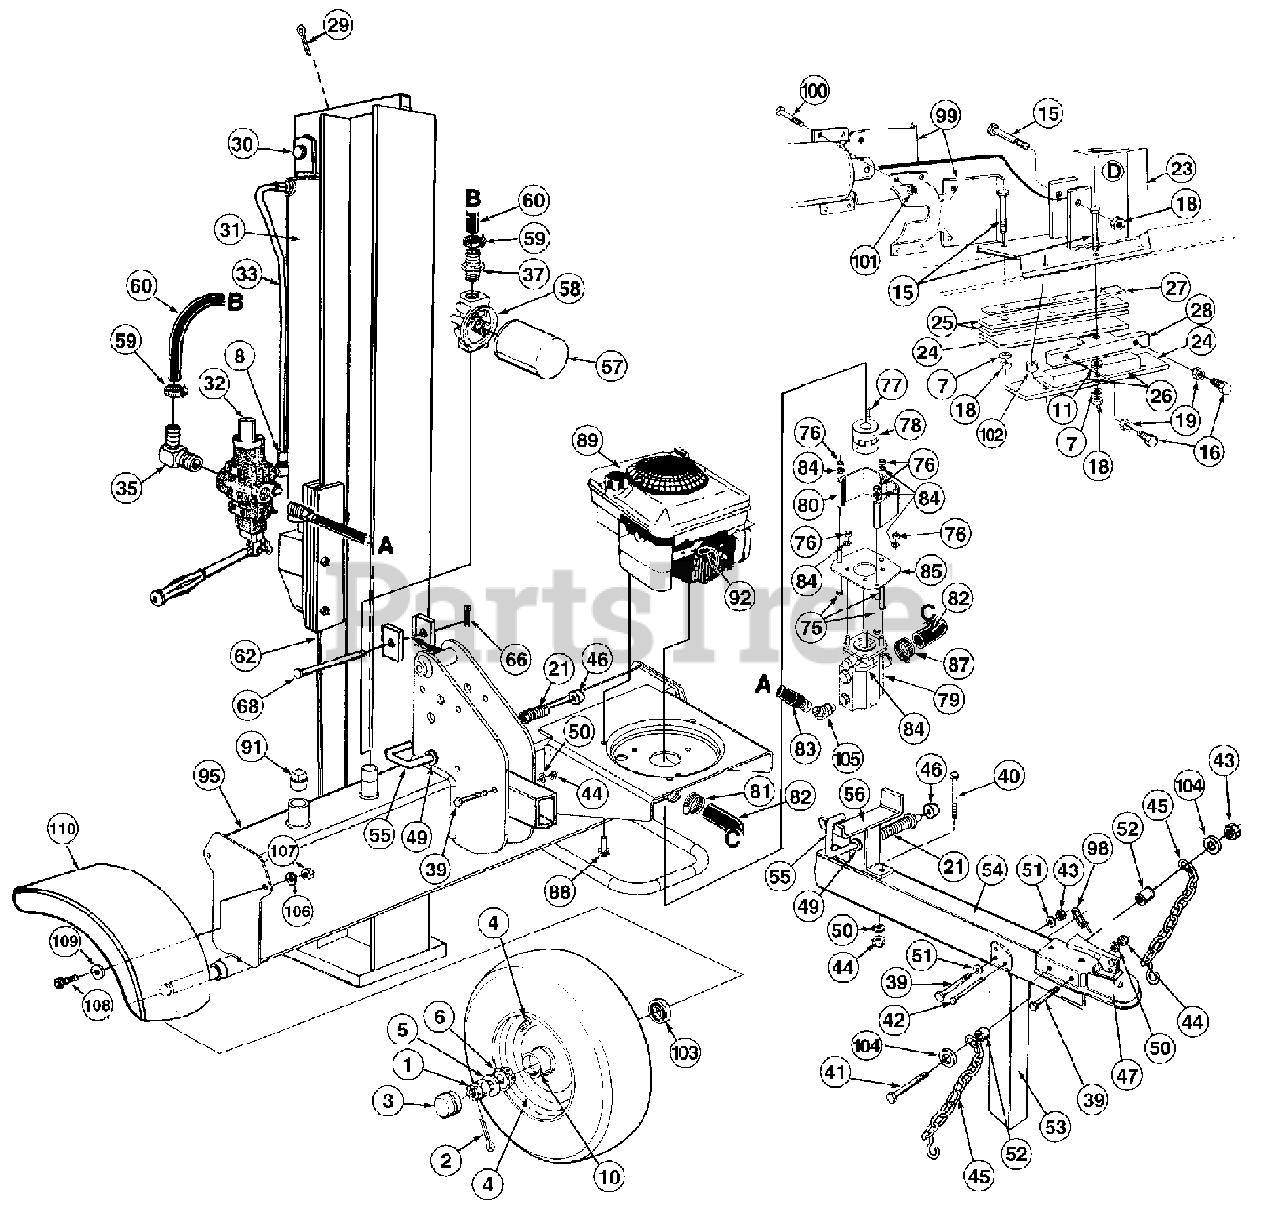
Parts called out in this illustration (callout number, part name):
1	Slotted Nut 3/4-16 Thd.
2	Cotter Pin 5/32" Dia. x 1-1/4" Lg.
3	Hub Cap
5	Fl-Wash. .76" I.D. x 1.5" O.D.
6	Bearing Cone
7	L-Wash. 1/2" I.D.
8	90° Solid Male Adapter
10	Bearing Cup
11	Fl-Wash. .531" I.D. x .94" O.D.
15	Hex Bolt 1/2-20 x 2.75" Lg. (Grd 8)
16	Hex Bolt 3/8-24 x 1.5" Lg.
18	Hex L-Nut 1/2-20 Thd.
19	Hex Jam Nut 3/8-24 Thd. (Grd 5)
21	Comp. Spring 4" Lg.
29	External Cotter Pin
30	Cylinder Mounting Pin
33	Metal Pressure Tube
35	Return Elbow
37	3/4" Hose Barb.
39	Hex Bolt 3/8-16 x 3" Lg.
40	Hex Bolt 3/8-16 x 4" Lg.
41	Hex Bolt 3/8-16 x 4" Lg. (Grd 5)
42	Clevis Pin 5/16 x 2.5" Lg.
43	Hex L-Nut 3/8-16 Thd.
44	Hex Nut 3/8-16 Thd.
45	Chain-Tow Hitch
46	Push Cap
47	Hitch Coupler
49	Fl-Wash. .635" I.D. x .93" O.D.
50	L-Wash. 3/8" I.D.
51	Fl-Wash. .406" I.D. x .75" O.D.
52	Spacer 3/8" I.D. x .625" O.D.
55	Locking Rod
57	Filter Element
58	Filter Head
59	Hose Clamp 5/8"
60	Return Hose 3/4" I.D. x 44" Lg.
68	Hinge Pin 1/2 x 4.8" Lg.
75	Hex Bolt 5/16-24 x 3.25" Lg.
76	Hex Nut 5/16-24 Thd.
77	Sq.-Key 3/16" x .75"
78	Flexible Coupling
79	Gear Pump
80	Coupling Shield
81	Hose Clamp
82	Suction Hose
83	High Pressure Hydraulic Hose
84	L-Wash. 5/16" I.D.
87	Hose Clamp
88	Hex Wash Hd. TT-Tap Scr. 3/8-16 x 1" Lg.
89	Engine
91	L-Vent Pipe Plug
92	Spark Plug Boot
101	Hex L-Nut 3/8-16 Thd.
102	Spacer 1/2" I.D. x .68" Lg.
103	Bearing Seal Only
104	Fl-Wash. 3/8" I.D. x .87" O.D.
105	45 degree Elbow
106	L-Wash. 5/16" I.D.
107	Hex nut 5/16-24 Thd.
108	Hex Bolt (5/16-24 x .75" Lg.
109	Fl-Wash .344" I.D. x .875" O.D.
